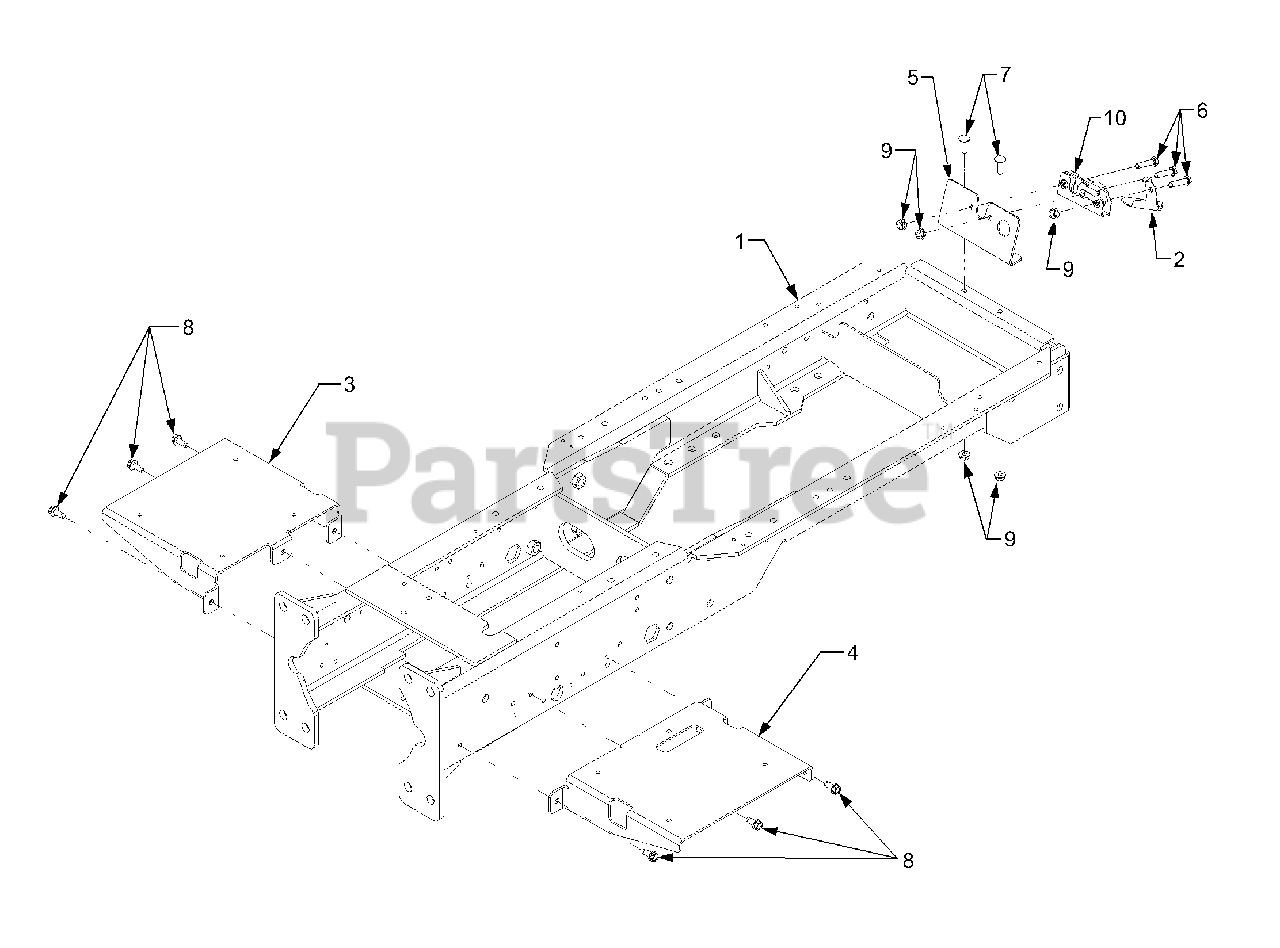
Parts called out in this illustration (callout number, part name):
2	Lever, Hood Latch
3	Bracket, Running Board Mtg. LH
4	Bracket, Running Board Mtg. RH
5	Bracket, Hood Latch Mtg
6	Screw, Hex Cap, 5/16-18 x 1.375 GR5
7	Screw, Carriage, 5/16-18 x 1.0
7	Screw, Carriage, 5/16-18 x .75
8	Screw, Hex Wash. Hd. 5/16-18 x .75
9	Nut, Hex Flange Lock, 5/16-18
10	Latch, Hood
